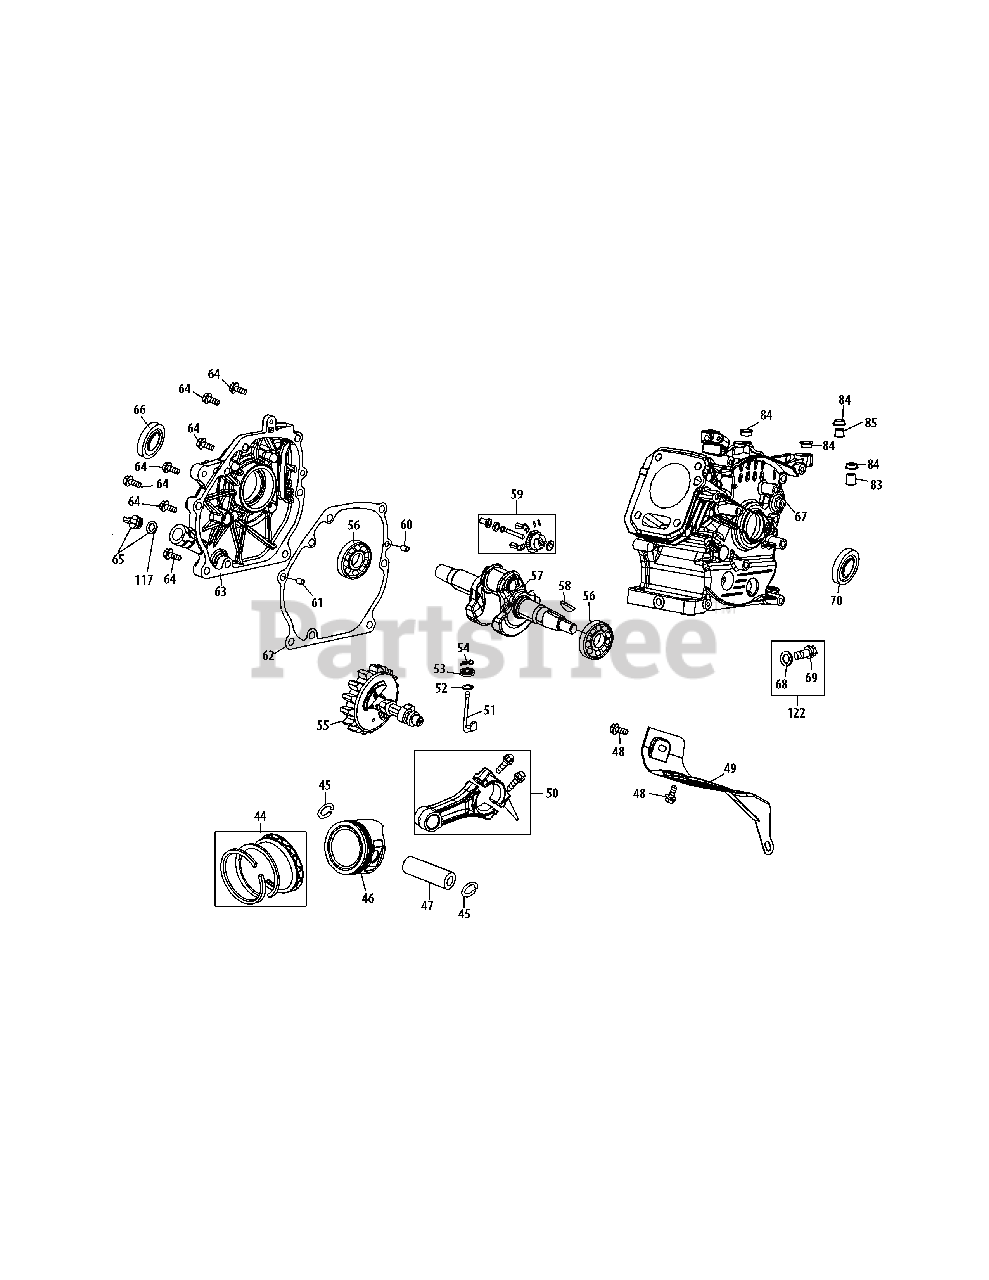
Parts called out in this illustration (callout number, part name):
44	Piston Ring Set
45	Piston Pin Snap Ring
46	Piston
47	Piston Pin
48	Bolt M6×12
49	Air Shield
50	Connecting Rod Assembly
51	Governor Arm Shaft
52	Washer 5.2×1.9
53	Governor Seal
54	Cotter Pin
55	Camshaft Assy.
56	Radial Ball Bearing, 6205
57	Crankshaft Assembly
58	Woodruff Key
59	Governor Gear/Shaft Assembly
60	Dowel Pin 7×14
61	Dowel Pin 9×14
62	Crankcase Cover Gasket
63	Cover Comp, Left Crankcase
64	Bolt M8×32
65	Dipstick Assembly
66	Oil Seal, 25×41.25×6
67	Short Block
68	Washer 10×16×1.5
69	Oil Drain Plug
70	Oil Seal 25×41.25×6
83	Grommet 8.5 x 24.5
84	Rubber Seat
85	Grommet 8.5 x 17
117	Oil Fill Plug Assembly
122	Oil Drain Plug & Washer Assembly
